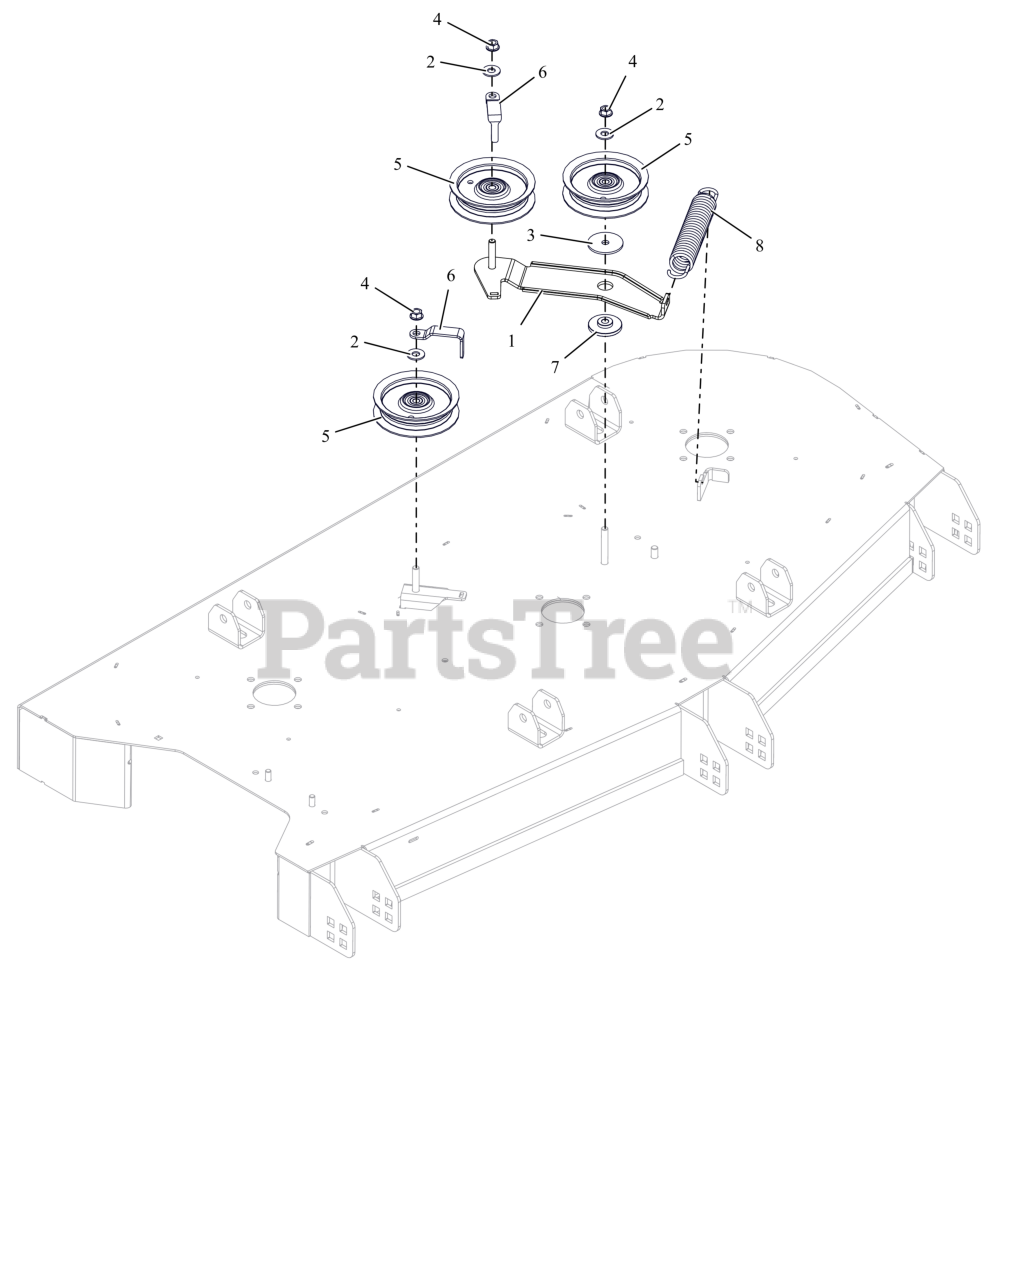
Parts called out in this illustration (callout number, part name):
1	WLDMT, TENSIONER ARM (BLACK)
2	WSHR,FLT .438X1.00X.083 ZCC
3	WSHR-FL-STL 0.406X2X0.125 ZCC
4	NUT-LK-CTR-FLG .375-16 GF ZCC
5	IDLER, FLAT - 4.06" X .75"
6	FINGER, BELT (BLACK)
7	BSHG-FLG .406X.88X.43X.25
8	SPRG, EXTENSION
